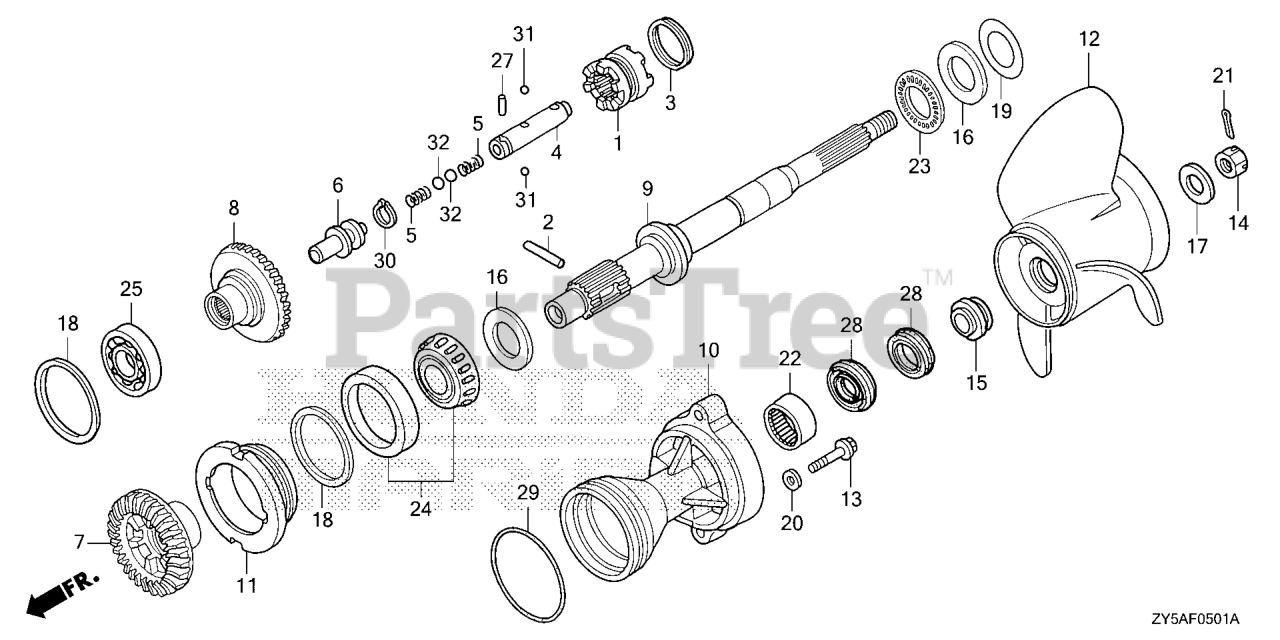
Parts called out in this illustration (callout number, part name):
1	SHIFTER, CLUTCH
2	PIN, SHIFTER (8X47)
3	RING, CROSS PIN
4	SLIDER, SHIFT
5	SPRING, SHIFT
6	PLATE, SHIFT
7	GEAR, BEVEL (FORWARD 30T) (COUNTER ROTATION)
8	GEAR, BEVEL (RVS. 30T) (COUNTER ROTATION)
9	SHAFT, PROPELLER (COUNTER ROTATION)
10	HOLDER, PROPELLER SHAFT *NHB14M* (AQUA MARINE SILVER METALLIC)
10	HOLDER,PROP*NH565*
11	HOLDER, BEARING (COUNTER ROTATION)
12	PROPELLER, THREE-BLADE (14-1/2X15) (C/R)
12	PROPELLER, THREE-BLADE (14-1/4X17) (C/R)
12	PROPELLER, THREE-BLADE (14X19) (C/R)
12	PROPELLER, THREE-BLADE (14X21) (C/R)
12	PROPELLER, THREE-BLADE (14-1/2X23) (C/R)
13	BOLT, FLANGE (10X40)
14	NUT, CASTLE (18MM)
15	WASHER, PROPELLER THRUST
16	WASHER, THRUST BEARING
17	WASHER, PROPELLER
18	SHIM A, BEVEL (0.10)
18	SHIM B, BEVEL (0.15)
18	SHIM C, BEVEL (0.30)
18	SHIM D, BEVEL (0.50)
19	SHIM A, THRUST (0.10)
19	SHIM B, THRUST (0.15)
19	SHIM C, THRUST (0.30)
19	SHIM D, THRUST (0.50)
20	WASHER, PLAIN (10MM)
21	PIN, SPLIT (4.0)
22	BEARING, NEEDLE (30X37X26)
22	BEARING (30X37X26)
23	BEARING, THRUST (F)
24	BEARING, TAPER (50X90X28)
25	BEARING, RADIAL BALL (50X90X20)
26	BEARING, NEEDLE (25X32X26)
27	ROLLER (3X12.8)
28	SEAL, WATER (30X45X7)
29	O-RING (105X3.1)
30	CIRCLIP (OUTER) (14MM)
31	BALL, STEEL (#7) (7/32)
32	BALL, STEEL (#9) (9/32)
